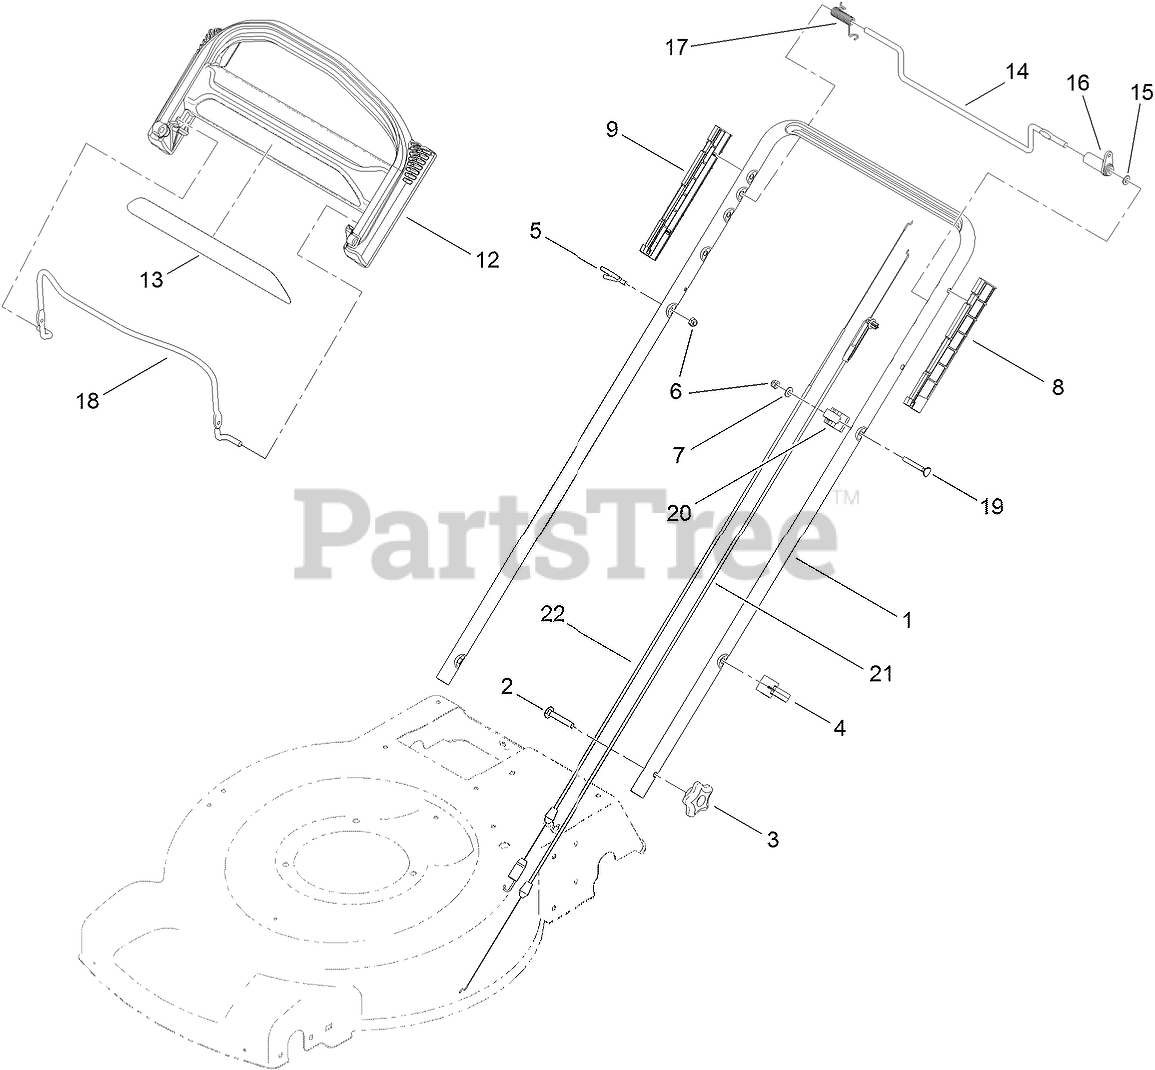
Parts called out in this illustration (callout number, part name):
2	Screw-CARR
3	KNOB-HANDLE
4	GUIDE-CABLE
5	GUIDE-ROPE
6	NUT-LOCK, NI
7	WASHER-FLAT
8	GUIDE-LH
9	GUIDE-RH
12	HANDLE-CONTROL
14	BAR-CONTROL, TRACTION
15	WASHER-PLAIN
16	LEVER-TRACTION
17	Spring-Torsion
18	Bail-Brake
19	SCREW
20	ANCHOR-CABLE
21	CABLE-BRAKE
22	CABLE-TRACTION
